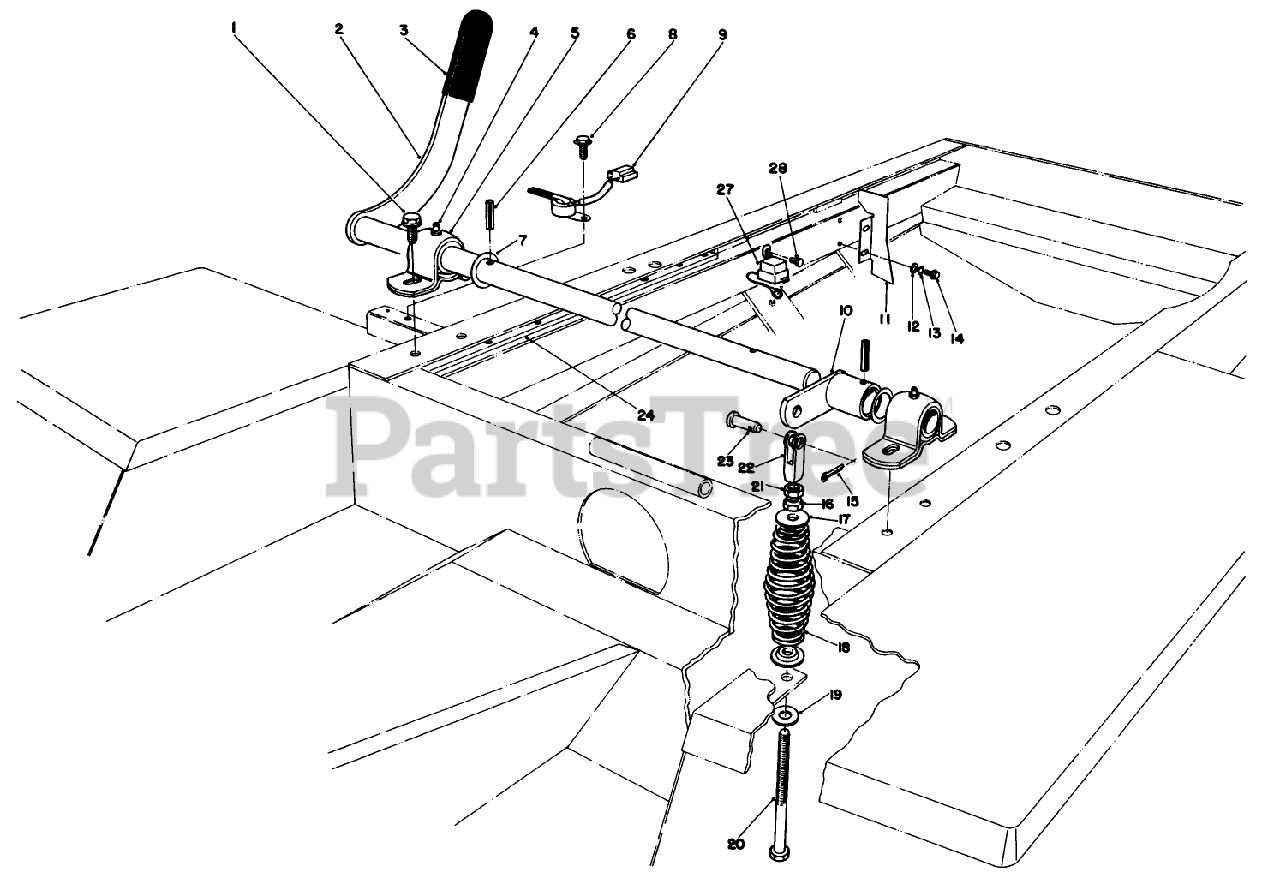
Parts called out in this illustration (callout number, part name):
1	SCREW-HHF
2	P.T.0. Lever
3	GRIP-HANDLE
4	FITTING-GREASE
5	BEARING
6	PIN-SPRING
7	THRUST WASHER
8	SCREW-THD FRM,HWH
9	SWITCH ARM
10	Arm-Engagement
11	Shield-Heat
12	WASHER-PLAIN
13	WASHER-LOCK
14	SCREW-HWHTF
15	PIN-COTTER
16	NUT-HEX
17	SPRING RET TOP
18	COMP SPRING
19	WASHER
20	SCREW-ADJUSTING
21	NUT-HJ
22	PLUG-PIPE, SQH
23	PIN-CLEVIS
24	Bar Frame Rail
27	RELAY
28	SCREW-HWH
